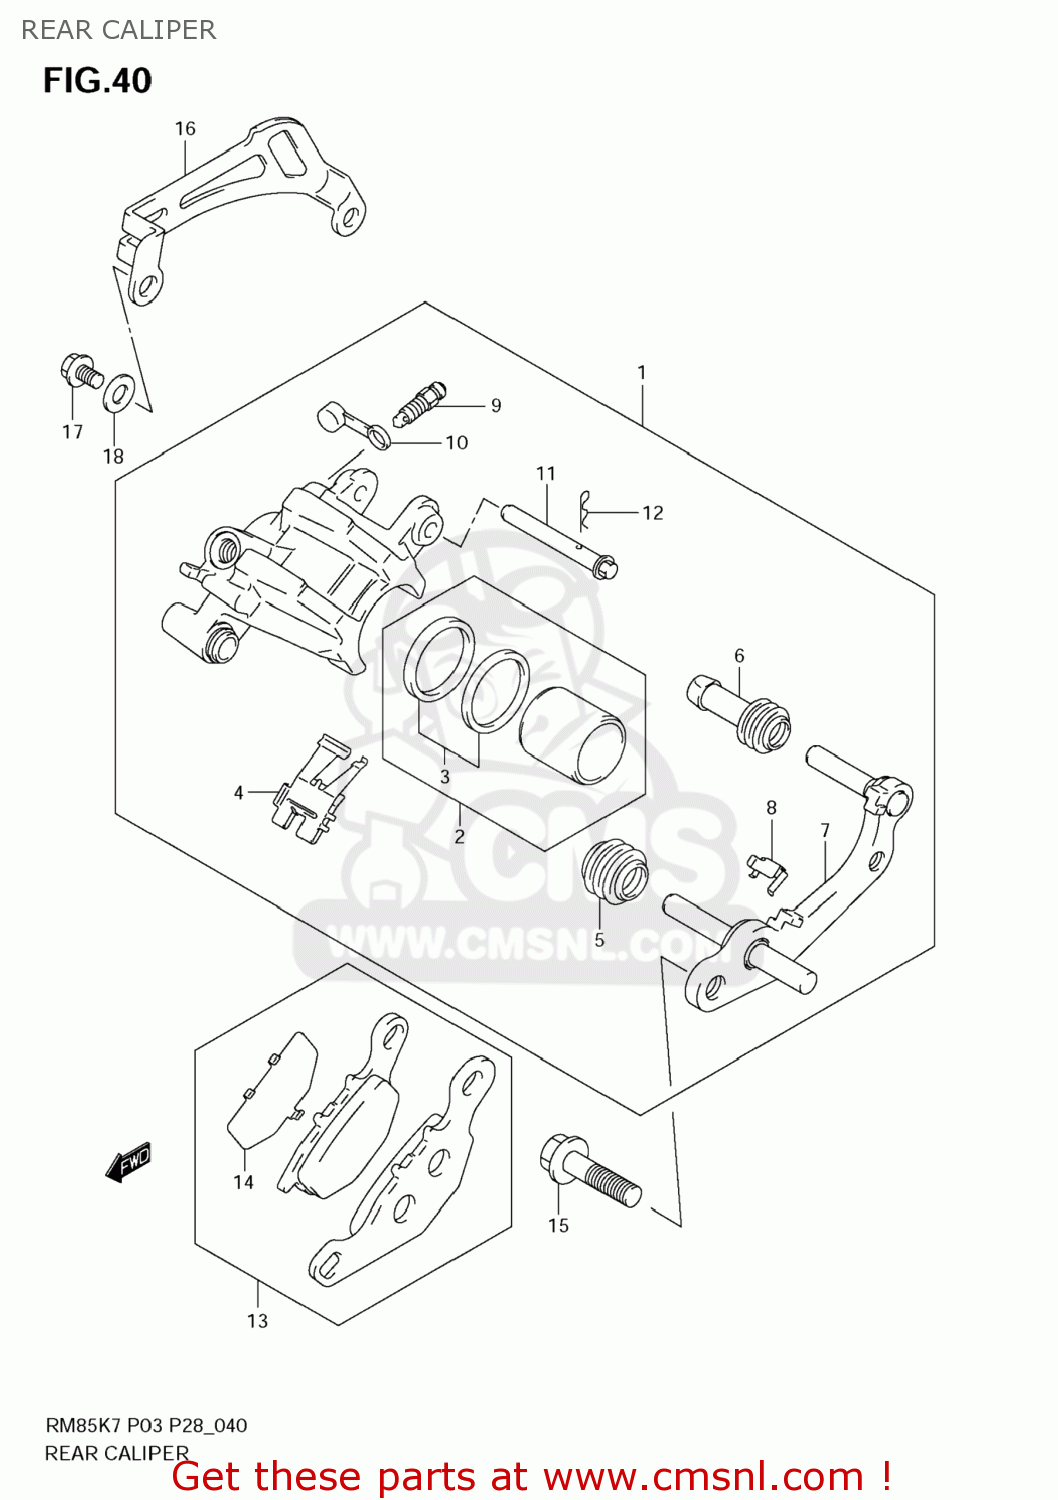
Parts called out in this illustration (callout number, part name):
1	CALIPER ASSY,RR
2	PISTON SET
3	SEAL SET,PISTON
4	SPRING,PAD
5	BOOT,AXLE
6	INSULATOR,AXLE
7	CARRIER,CALIPER
8	GUIDE,PAD
9	BLEEDER
10	CAP,BLEEDER
11	PIN,PAD
12	CLIP,PAD PIN
13	PAD & SHIM SET (NAS)
14	SHIM,PAD
15	BOLT(8X18)
16	GUARD,RR CALIPER
17	BOLT(6X10)
18	WASHER
